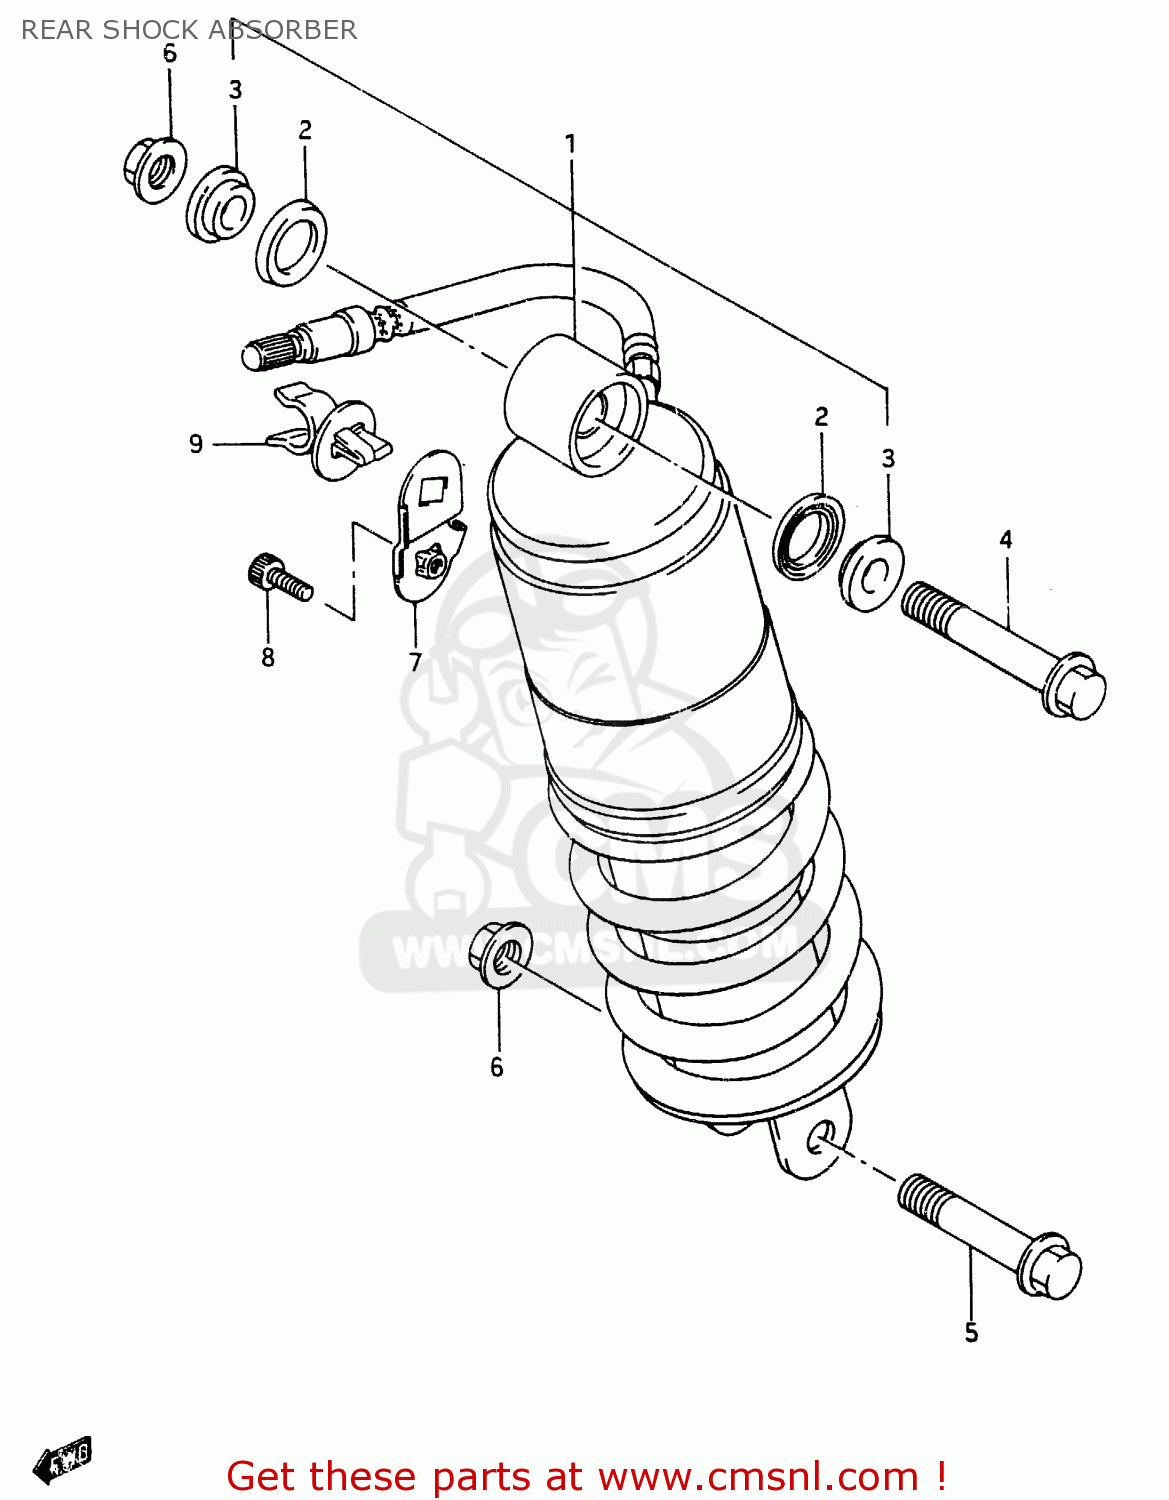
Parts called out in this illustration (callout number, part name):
1	ABSORBER ASSY, REAR SHOCK
2	DUST SEAL
3	SPACER
4	BOLT(10X58)
5	BOLT(10X50)
6	NUT
7	BRACKET, ABSORBER HOSE
8	BOLT
9	CLAMP
